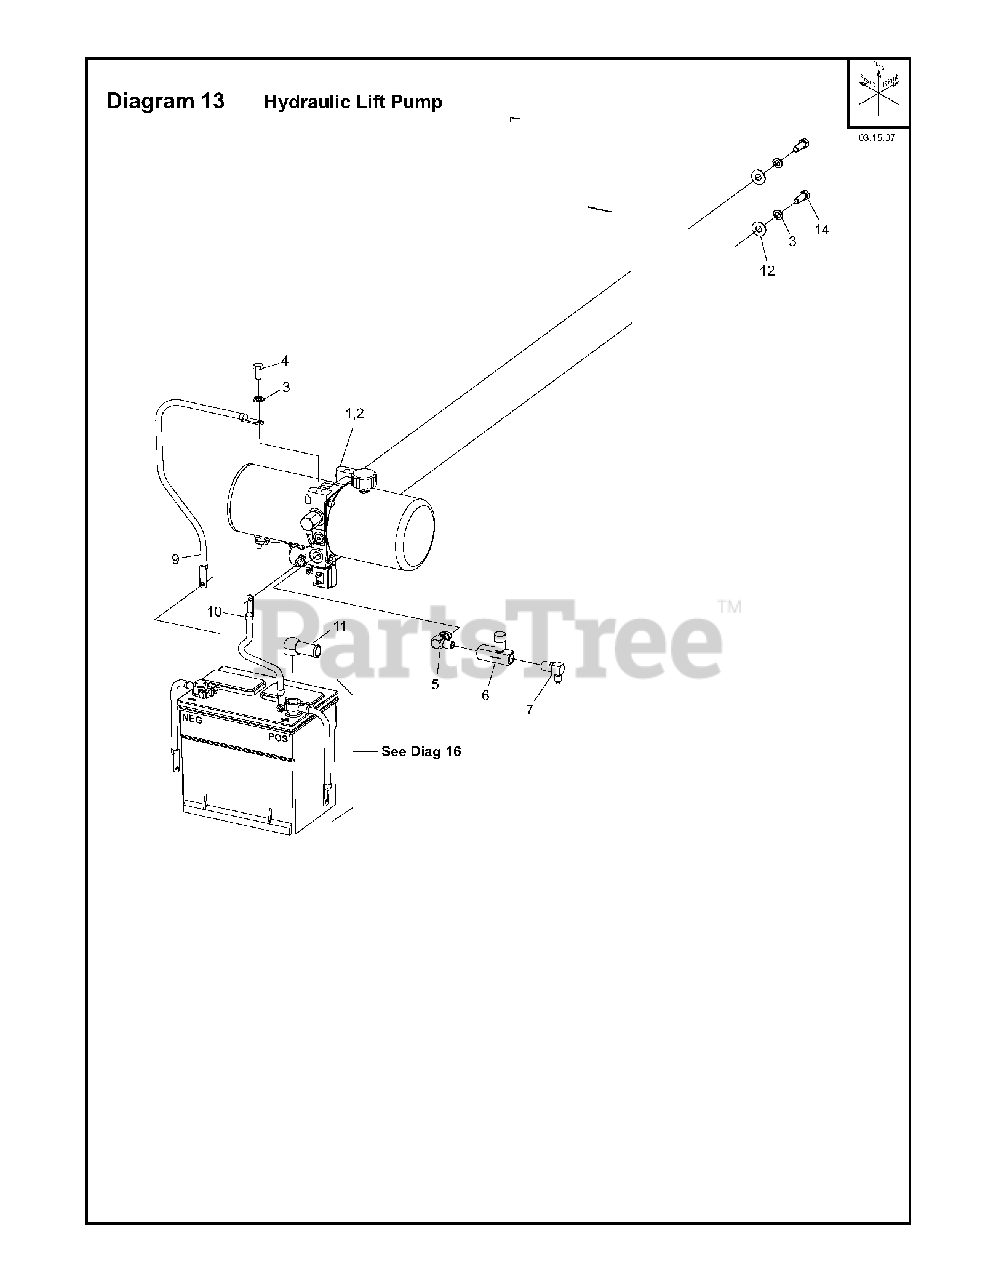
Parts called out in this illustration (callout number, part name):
1	PUMP
3	LOCKWASHER. SPLIT .375
4	HHCS. .375-16 x .75 GR 5 Z/P
5	FITTING. 6806-6-4
8	CABLE TIE. PLASTIC 8 IN X .094
10	BATTERY CABLE. POS 12"
13	LOCKWASHER. SPLIT .375
14	HHCS. .375-16 x 1 GR 5 Z/P
